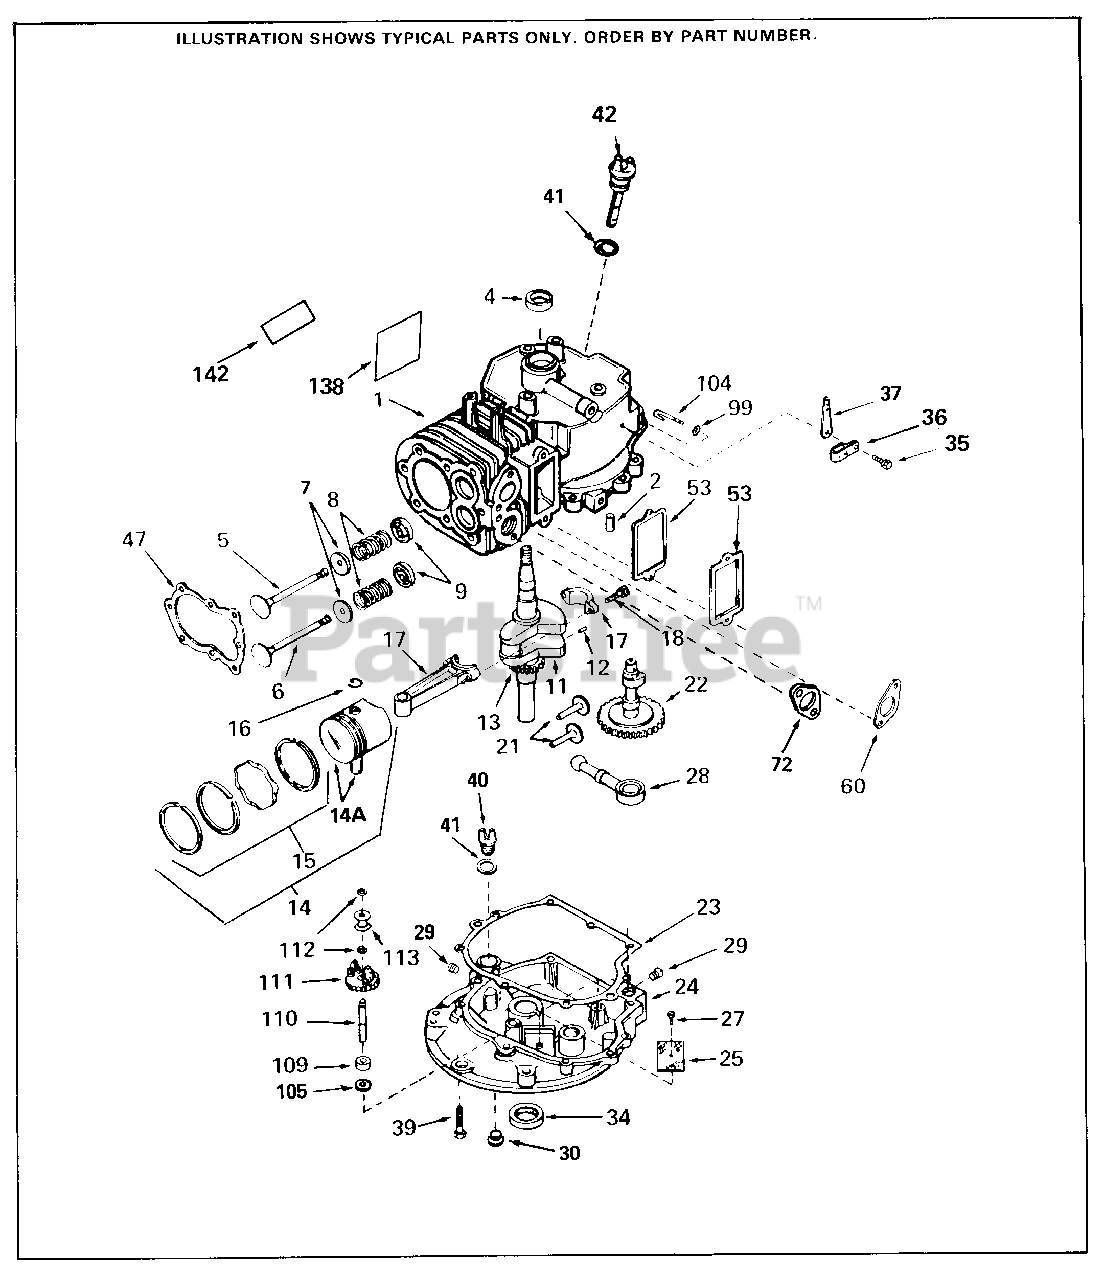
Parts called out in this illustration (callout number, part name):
1	"Cylinder (Incl. 2 & 4) (2-5/8" Bore)
2	Dowel Pin
4	Seal, Oil
5	Intake Valve (Std.) (Incl. 9)
5	Intake Valve (1/32" OS) (Incl. 9)
6	Exhaust Valve (Std.)(Incl. 151)
6	Exhaust Valve (1/32" OS) (Incl. 151)
7	Valve Spring Cap
8	Valve Spring
9	Cap, Lower valve spring
11	Crankshaft
12	Pin, Crankshaft gear only)
13	Crankshaft Gear Early production only
14	Piston, Pin & Ring Set (Std.) 2-5/8"B ore
14	Piston, Pin & Ring Set (.010" OS)
14	Exhaust Valve (1/32" OS)
14A	Piston & Pin Ass'y. (Std.)(Incl. 16) 2-5/8"
14A	Piston & Pin Ass'y. (.010" OS) Incl. 16
14A	Piston & Pin Ass'y. (.020" OS) Incl. 16
15	Ring Set (Std.) (2-5/8" Bore)
15	Ring Set (.010" OS)
15	Ring Set (.020" OS)
16	Piston Pin Retaining Ring
17	Rod, Connecting (Incl. 18)
18	Bolt, Connecting rod (2 pcs.)
21	Lifter, Valve
22	Camshaft
23	Gasket, Mounting flange
24	Mounting Flange Incl. 29,30,34,40,41, 105,110
28	Pump Assy., Oil
29	Oil Drain Plug (Sq. hd., 1/4-18)red)
29	Oil Drain Plug (Sq. hd., 1/4-18)As re q)
30	Oil Drain Plug (Sq. hd., 1/4-18)ed)
30	Oil Drain Plug (Sq. hd., 1/4-18)As re q)
34	Oil Seal
35	Screw, 8-32 x 5/16"
36	Clamp, Governor lever
37	Lever, Governor
39	Screw, 1/4-20 x 1-1/4"
40	Oil Fill Plug (Incl. 312) also availa ble in Packaged Part #740079
41	Oil Fill Plug Gasket
42	Dipstick, Oil (Incl. 41)
47	Gasket, Cylinder head
53	Valve Cover Gasket
60	Intake Pipe Gasket
99	Flat Washer
104	Rod, Governor (Incl. 99)
105	Washer, Flat
109	Spacer, Governor gear (Incl. 105)
110	Shaft, Mechanical governor
111	Gear Assy., Governor (Incl. 105)
112	Retaining Ring
113	Spool, Governor
138	Decal, Instruction
